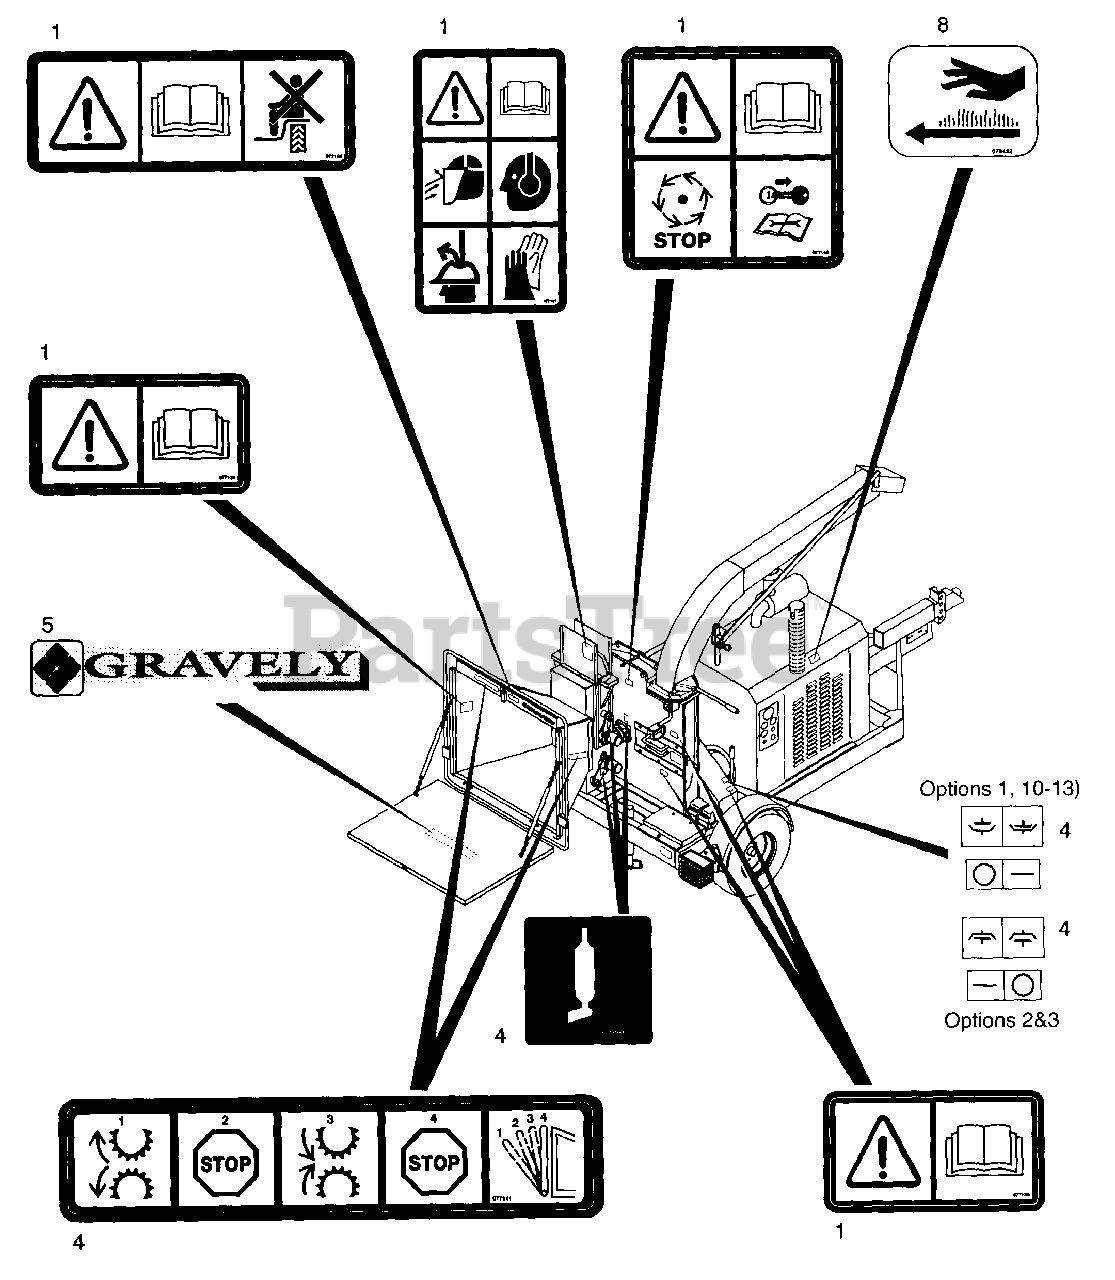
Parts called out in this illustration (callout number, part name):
1	Decal Set-Chipper CE
4	Decal Set-Chipper Black/White
5	Decal-Gravely Name/Logo Set (2 Large and 1 Small)
8	Decal-Hot Surface
